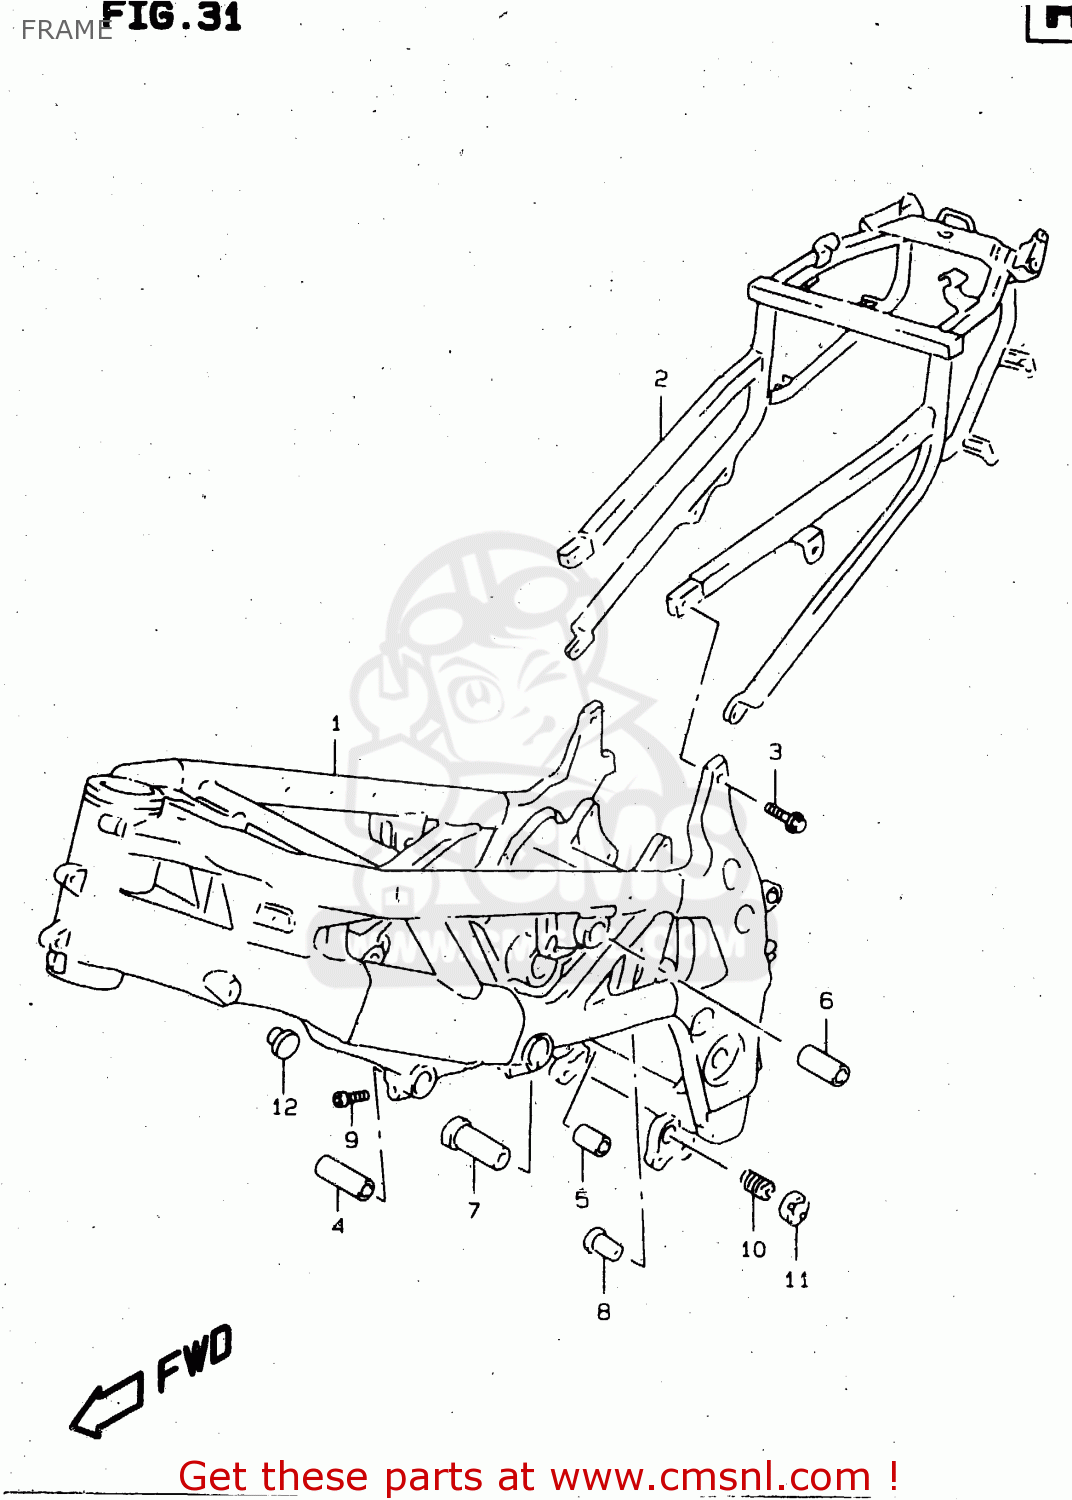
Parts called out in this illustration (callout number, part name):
1	FRAME
2	RAIL,SEAT
3	BOLT(10X30)
4	SPACER,ENG HEAD MTG FR,L
5	SPACER,ENG HEAD MTG RR,R
6	SPACER,ENG HEAD MTG RR,L
7	SPACER,CRANK CASE MTG FR,L
8	SPACER,ENGINE MOUNTING
9	BOLT
10	BOLT,CRANKCASE ADJUST
11	NUT,CRANKCASE ADJUST
12	CAP
